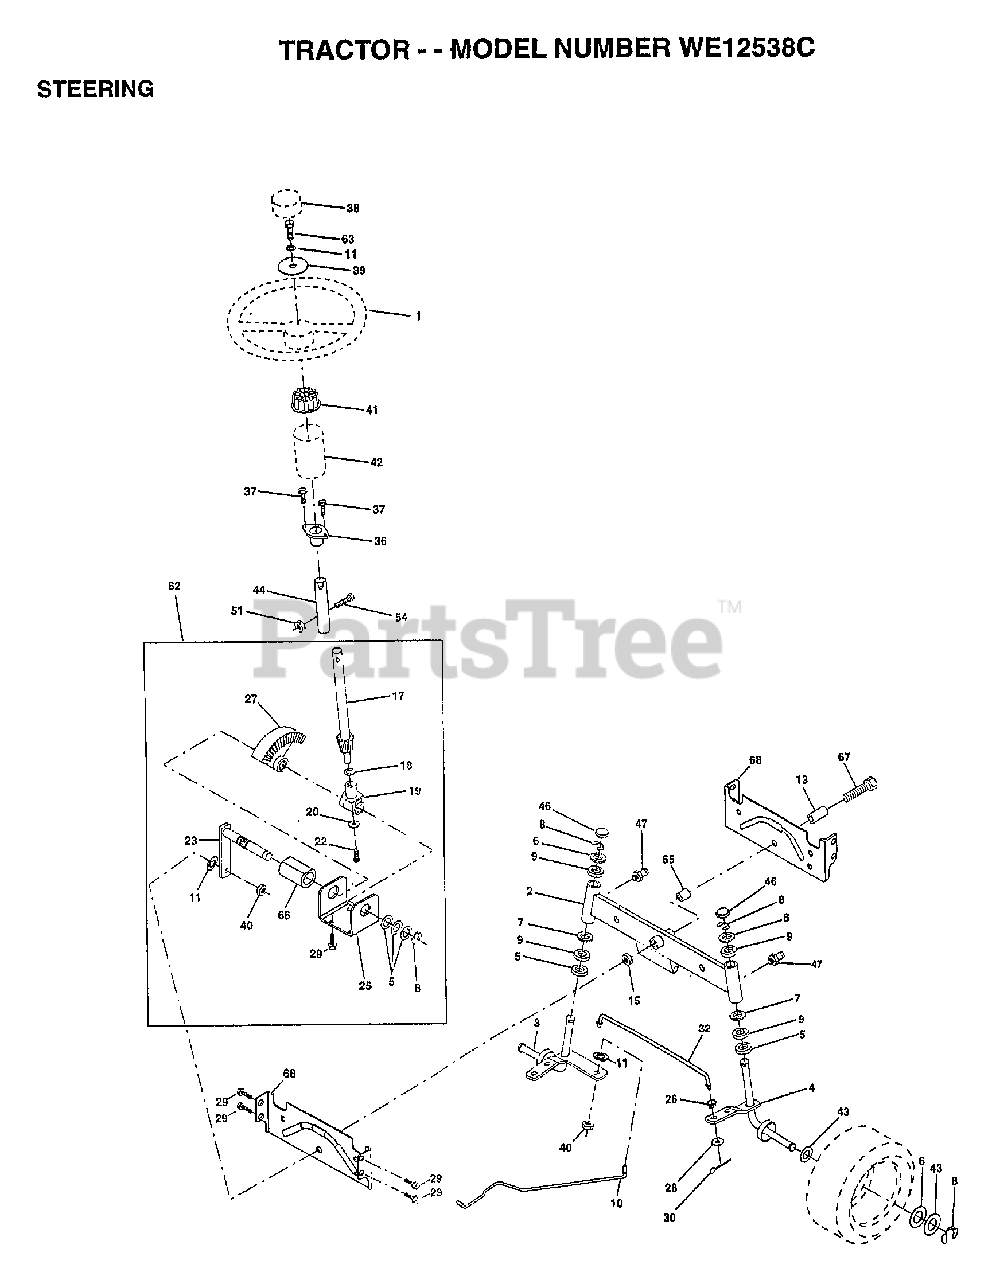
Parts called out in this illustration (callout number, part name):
1	WHEEL STR AYP BLK
2	AXLE ASM
3	SPINDLE.ASM.LH
4	"SPINDLE ASM,RH"
5	WASHER .T
6	WASHER
7	WASHER
8	RING
9	COL. SRTG. BEAR.
10	DRAGLINK-STAMPED
11	LOCKWASHER
13	BEARING AXLE
15	"NUT-LOC,FLANGE LT"
17	SHAFT ASM STEERIN
18	THRUST WASHER
19	SUPPORT.SHAFT
22	SCREW HEX SOC1/4-
25	BRKT-STEERING
26	BUSHING.DRAGLINK
27	GEAR SECTOR
28	WASHER
29	SCREW
30	COTTER PIN
32	TIE ROD
36	BUSHING.STEERING
37	"SCREW-TT,10-32 FL"
38	CAP STEER AYP
39	WASHER T
40	GRIPCO NUT
41	ADAPTER LT
42	BOOT.STEER.PL
43	WASHER
44	EXT SHAFT STEERIN
46	CAP
47	ZERK M
51	NUT
54	BOLT
62	KIT STEERING ASM
63	BOLT
65	SPACER AXLE
66	"BEARING-ARM,PITMA"
67	BOLT
68	BRACE AXLE
